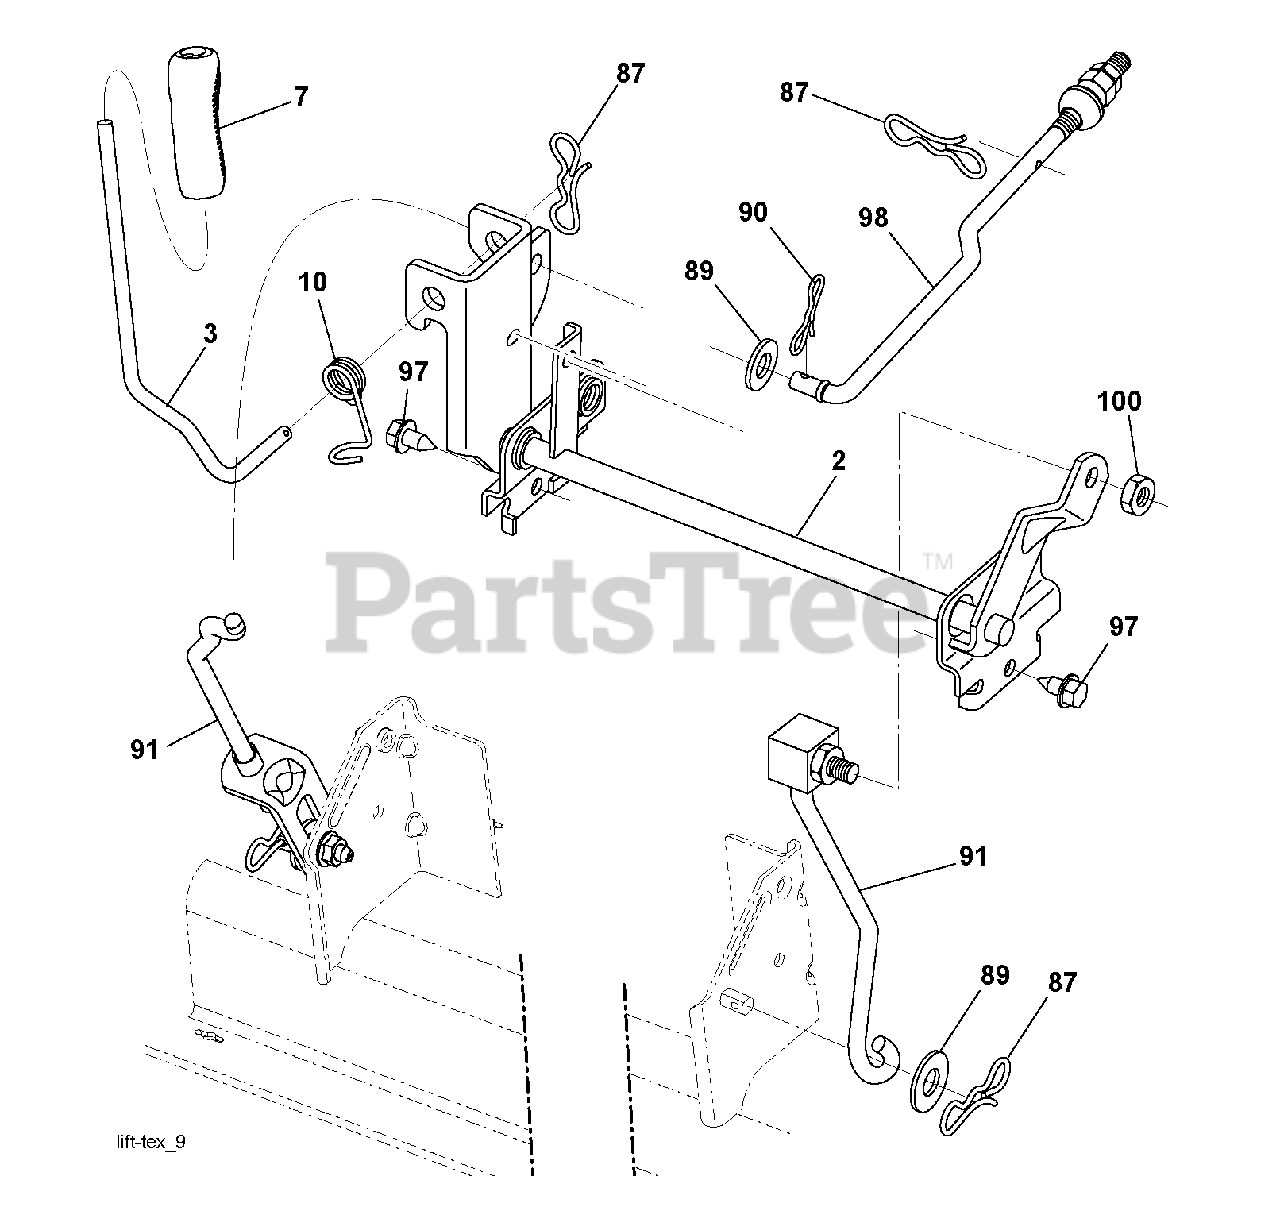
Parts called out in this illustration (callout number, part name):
2	SHAFT.ASM.LIFT.CROSS.H
3	LEVER.LIFT.HANDLE.LT
7	GRIP.LEVER.5625.ID
10	SPRING.TORSION.LIFT.HANDLE
87	PIN.COTTER.7/16.BOW TI
89	WASHER.CLEAR.ZINC
90	PIN.COTTER.5/16.BOW TI
91	LINK.ASM.LIFT.REAR
97	SCREW 3/8-16X3/4
98	LINK.ASM.SUSP.FRONT.MW
100	LOCKNUT
